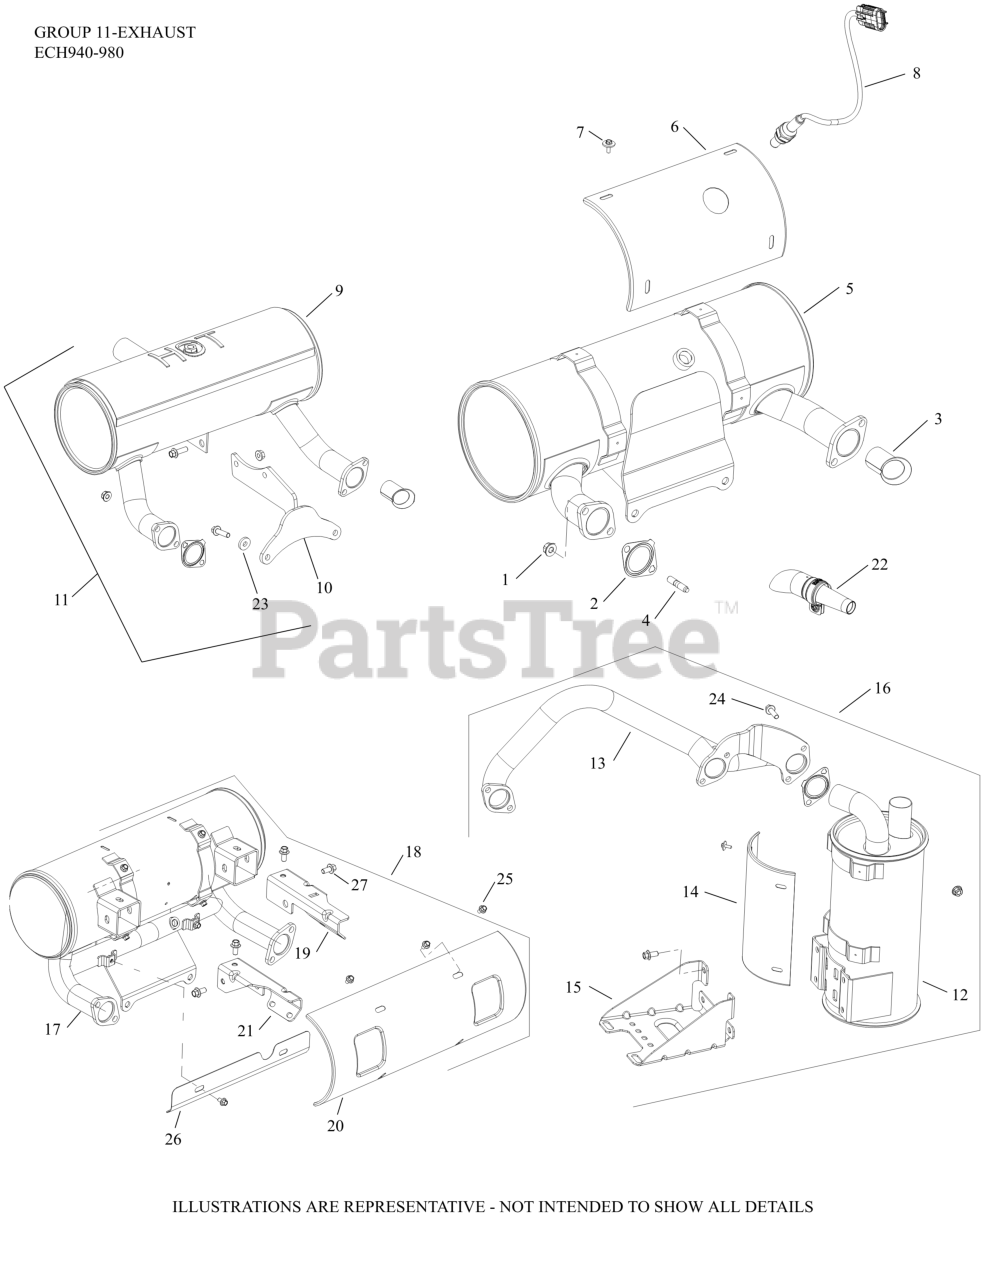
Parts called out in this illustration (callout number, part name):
1	NUT, HEX FLANGE LOCK (M8)
2	GASKET, EXHAUST
3	LINER, EXHAUST PORT
8	SENSOR, OXYGEN (M18 x 1.5 THREADS)
